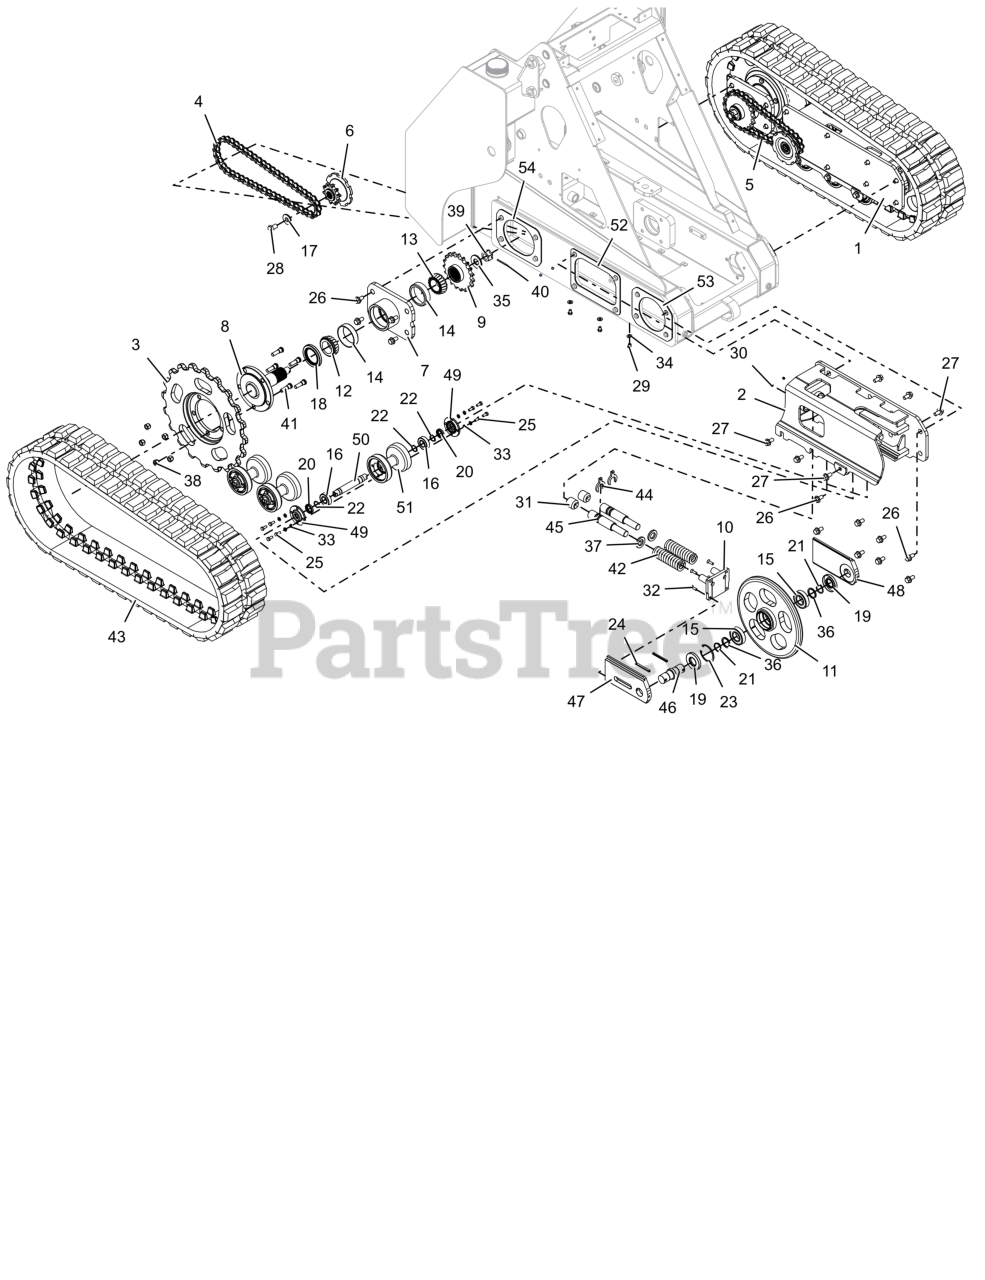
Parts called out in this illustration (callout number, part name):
1	MOUNT, IDLER LH - TRACK (RED)
2	MOUNT, IDLER RH - TRACK (RED)
3	WHEEL, DRIVE - TRACK (BLACK)
4	CHAIN, ROLLER -RS80HT 50 PITCH
5	CHAIN, ROLLER -RS80HT 38 PITCH
6	SPROCKET, DRIVE - DT
7	WLDMT, HUB -TRACK (RED)
8	WLDMT, AXLE - TRACK (RED)
9	SPROCKET, DRIVEN -REAR #80 19T
10	PLATE, TENSION -TRACK (BLACK)
11	WHEEL, IDLER - TRACK
12	BRG, CONE 2.063 X 1.193
13	BRG, CONE 2.000 X 1.193
14	BRG, CUP 3.672 X .938
15	BRG-BALL 1.378x2.835x.669
16	BRG-BALL .984X2.04X.59
17	SPCR, FLANGE
18	SEAL, OIL - 2.50X3.756X.500
19	SEAL, OIL - 35MMX72MMX10MM
20	SEAL, OIL - 25MMX38MMX7MM
21	RING, RETAINING-EXTERNAL 35MM X 1.5MM
22	RING, RETAINING-EXTERNAL 25MM X 1.2MM
23	RING, RETAINING-INTERNAL
24	PIN-ROLL .312X3.00
25	BLT,HEX .31-18X.75 G5 ZCC
26	BLT, HEX-FLG 0.5-13X1 GR8 ZCC
27	BLT, HEX 0.5-20X1 G8 ZCC
28	BLT, HEX 0.625-18X1 GR5 ZCC
29	@BLT-HEX .38-16X.50 GR5 YWZC
30	SCR-SET, .312-18X.312 CUP SS
31	SCR-SET, 1.50-6X1.500 CUP
32	SCR, MCH .312-18X1.00 SFH ZCC
33	WSHR,LK-REG .312X.078 ZCC
34	WSHR,FLT .406X.812X.065 ZCC
35	WSHR, FLAT - HRD 1.01X2.25X.19
36	WSHR, FLAT - 1.380X1.750X.125
37	WSHR, FLAT -HRD 1.006X1.813X.25
38	NUT, WHEEL .50-20 ZCC
39	NUT, SLOTTED-1.00-14
40	PIN, CTR .18X2.00 EXTPRSQCT ZCC
41	STUD, WHEEL - .50-20 X 1.875LG
42	SPRG, COMPRESSION
43	TRACK, WIDE
44	CLIP, LOCKING (BLACK)
45	ROD, SPRG PUSHER
46	AXLE, IDLER -TRACK
47	PLATE, IDLER SIDE LH (BLACK)
48	PLATE, IDLER SIDE RH (BLACK)
49	CAP, ROLLER
50	AXLE, ROLLER -TRACK
51	WHEEL, ROLLER 200DT (BLACK)
52	GASKET, ACCESS TRANSMISSION
53	GASKET, FRONT TRANSMISSION
54	GASKET, REAR TRANSMISSION
